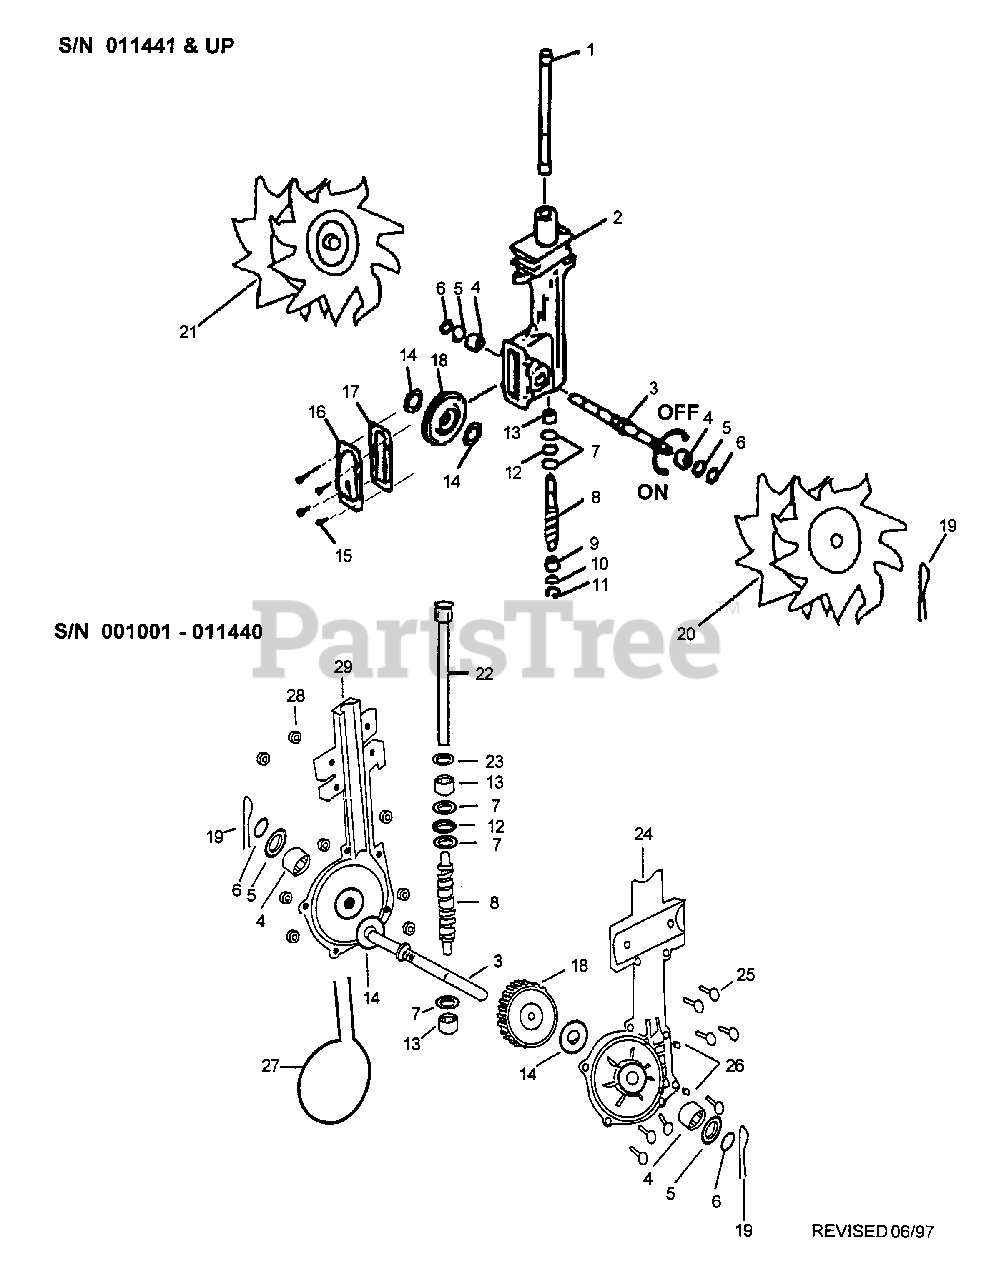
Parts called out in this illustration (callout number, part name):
1	DRIVESHAFT
2	CASE, GEAR
3	SHAFT, TINE
4	BEARING, WORM GEAR
5	SEAL, BEARING
6	RING, RETAINING
7	RACE, WORM BEARING
8	SHAFT, WORM
9	BEARING, BALL
11	RING, RETAINING - 15
12	BEARING, THRUST
13	BEARING, BALL
15	SCREW -- TAPPING
16	COVER, GEAR CASE
17	GASKET, GEAR CASE
18	GEAR - WORM
19	PIN, SPLIT
20	ROTOR, CULTIVATOR - RIGHT
21	ROTOR, CULTIVATOR - LEFT
22	DRIVESHAFT
24	CASE, GEAR - RIGHT
25	BOLT - 1/4 X 7/8"
26	CAP, OIL
27	GASKET, GEAR HOUSING
28	NUT - 1/4"
29	CASE, GEAR - LEFT
